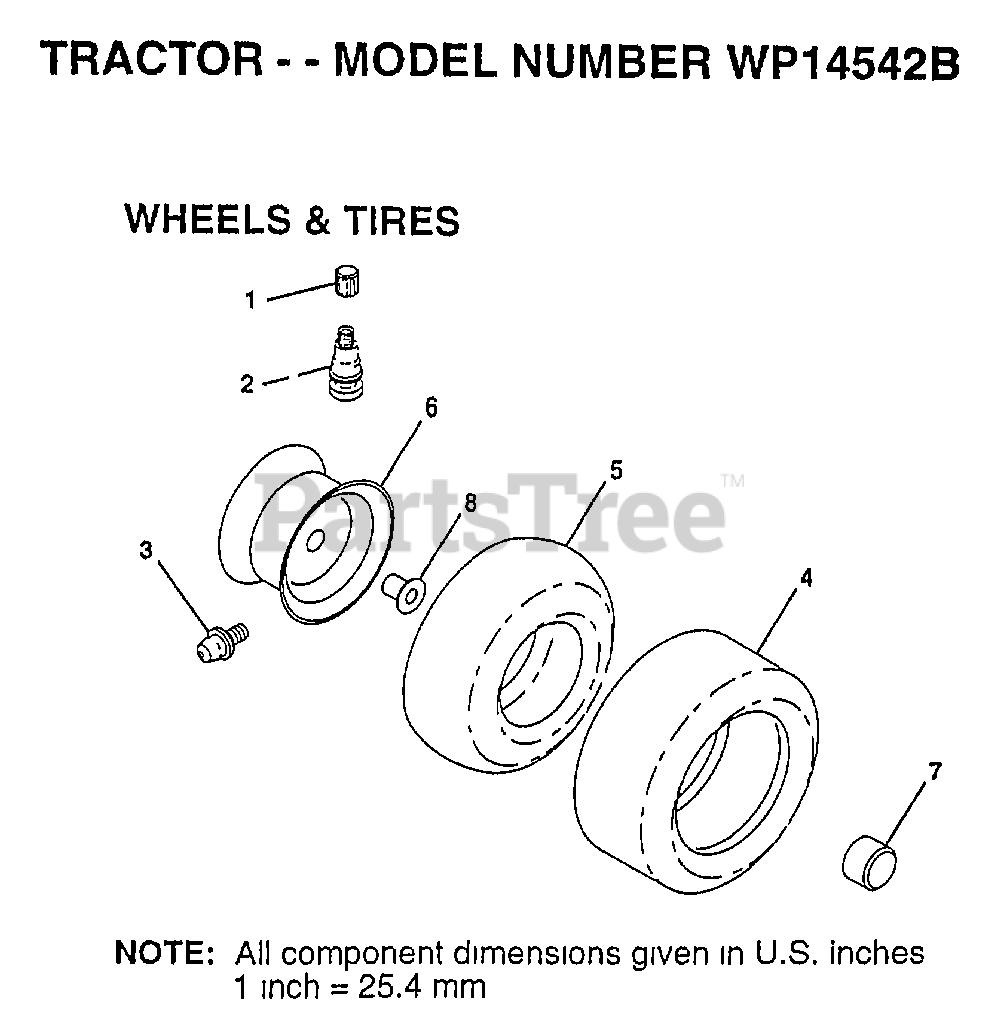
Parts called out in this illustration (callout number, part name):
1	VALVE CAP
2	VALVE STEM LT
3	FITTING LT
4	TIRE.20X8-8
5	TUBE.5.3/4.5/6
5	TUBE.18X9.5-8
6	"RIM,FRT T"
6	"RIM 8"""
7	HUB CAP
8	"FLANGE, BEARING"
